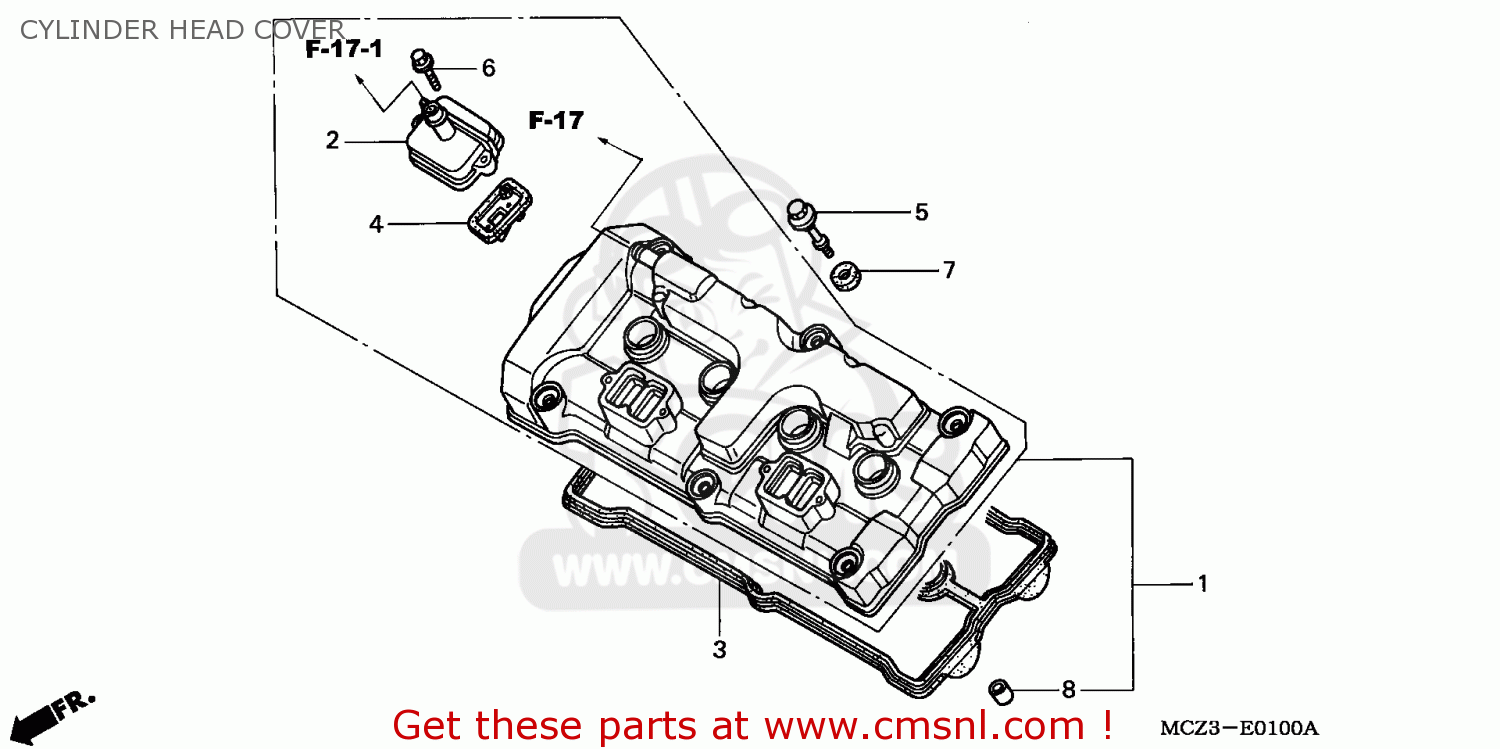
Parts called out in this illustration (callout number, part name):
1	COVER ASSY,CYLN H
2	COVER,REED VALVE
3	GASKET,HEAD COVER (NAS)
4	REED VALVE COMP
5	BOLT,HEAD COVER
6	BOLT,FLANGE,6X20
7	RUBBER,MOUNT
